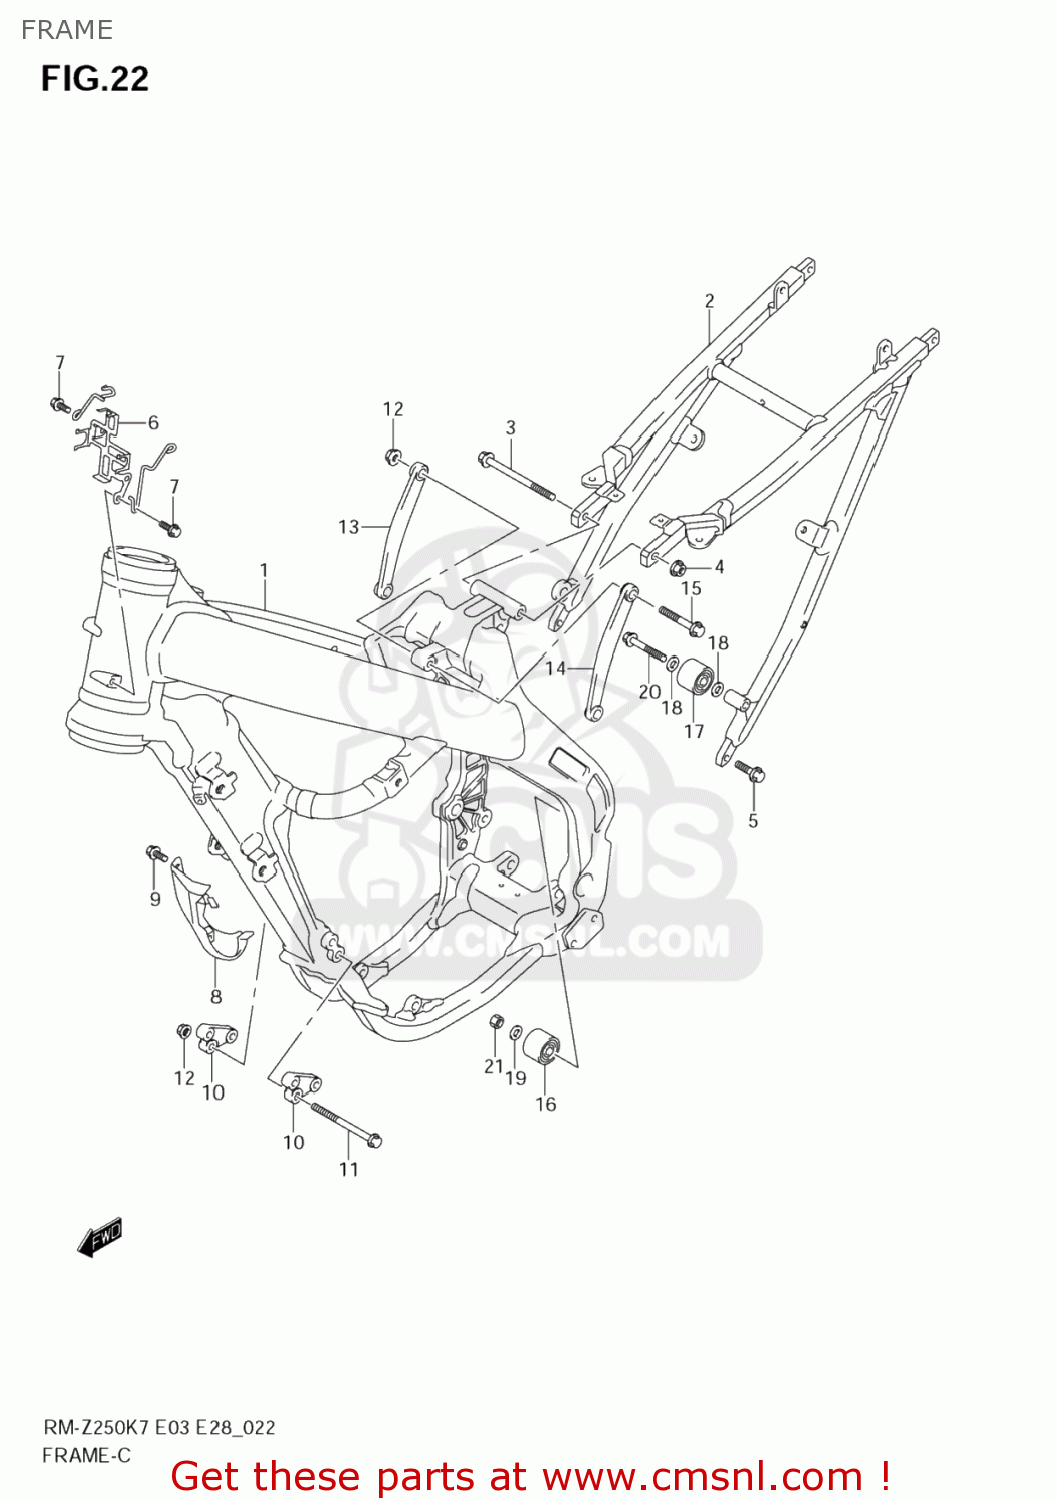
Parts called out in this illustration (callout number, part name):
1	FRAME
2	RAIL,SEAT
3	BOLT(8X110)
4	NUT
5	BOLT(8X20)
6	BRACKET,CDI
7	BOLT(6X10)
8	PROTECTOR,FRON
9	BOLT(6X16)
10	BRACKET,ENGINE MOUNTING FR
11	BOLT(8X95)
12	NUT
13	BRACKET,ENGINE MOUNTING UPR,R
14	BRACKET,ENGINE MOUNTING UPR,L
15	BOLT(8X55)
16	ROLLER,CHAIN
17	ROLLER,CHAIN
18	SHIM(8X12X1)
19	SHIM(8X16X1)
20	BOLT(8X45)
21	NUT
